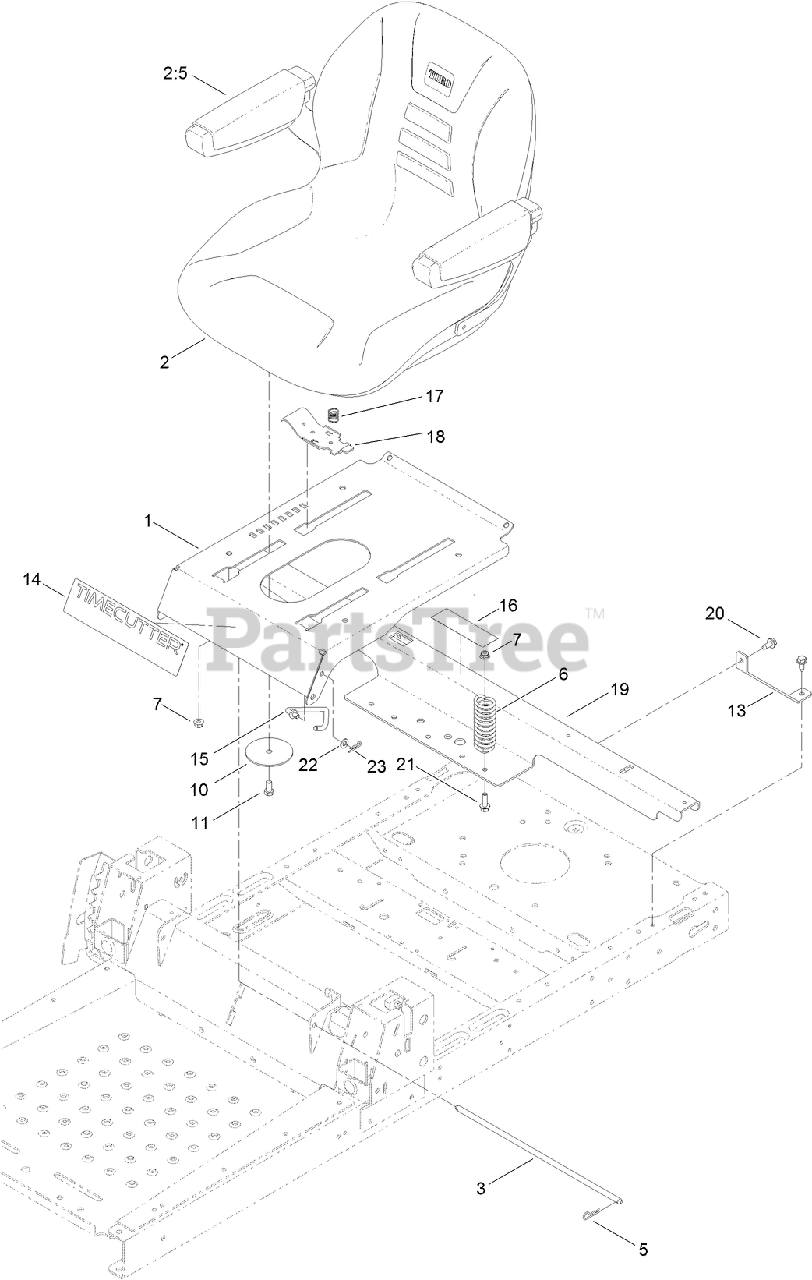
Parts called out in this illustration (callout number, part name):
1	PAN-SEAT
2	18 INCH SEAT ASM
2:5	ARMREST KIT
3	ROD-STOP
5	PIN-COTTER
6	SPRING-COMPRESSION
7	NUT-HF, NI
10	WASHER-SEAT
11	SCREW-HH
13	SUPPORT-TANK, REAR
14	DECAL-TIMECUTTER
15	STOP-SEAT
16	DECAL-SERVICE, CE
17	SPRING-COMPRESSION
18	LATCH-SEAT
19	SUPPORT-POD
20	SCREW-HWHTF
21	SCREW-HHF
22	WASHER-PLAIN
